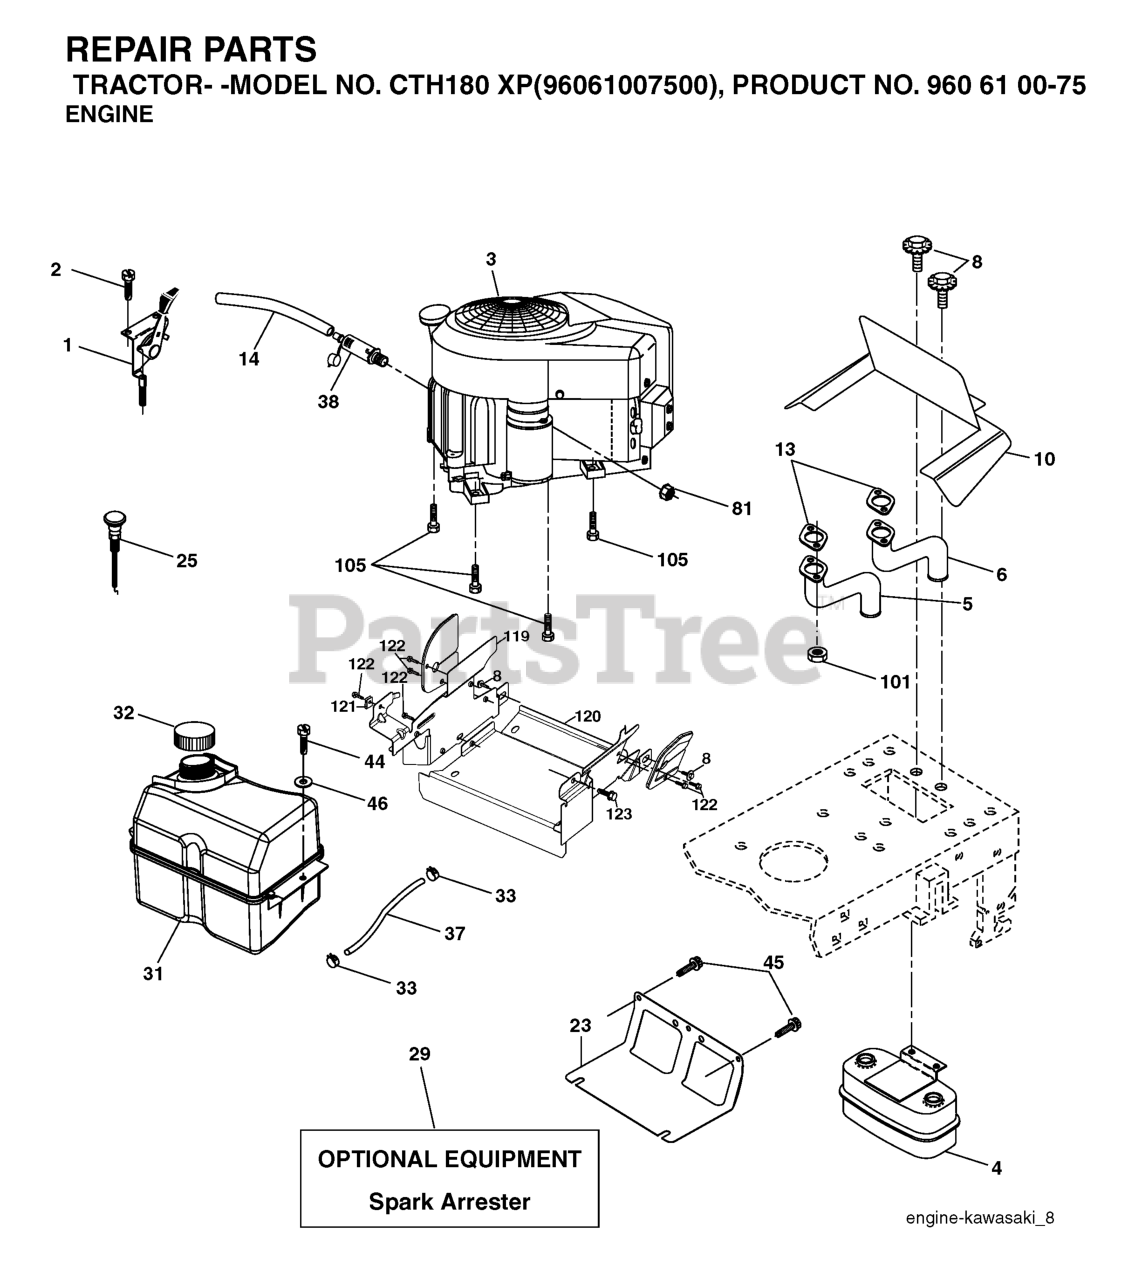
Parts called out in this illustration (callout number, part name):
1	CONTROL, THROTTLE
2	SCREW
4	MUFFLER.TWIN.CYL.LOW.TONE
5	EXHAUST.TUBE.LH.KAWASAKI.
6	EXHAUST.TUBE.RH.KAWASAKI.
8	BOLT.5/16-18UNCX3/4 W/SEMS.BLK
10	RP SHIELD HEAT MUFFLER
14	TUBE, DRAIN OIL ASM.
23	SHIELD.BROWNING.DBR.GUARD
29	KIT.SPARK ARRESTOR 794945 B&S
31	TANK FUEL
32	FUEL CAP
33	HOSE CLAMP
37	LINE.FUEL.20
44	SCREW HEXWSHR 1/4-20X3/4
45	SCREW, 3/8-16X3/4
81	NUT
101	NUT.HEX.FLANGE.TOPLOCK
105	SCREW 3/8-16X1
122	SCREW.1/4-20X5/8
123	SCREW, 5/16-18 X 1/2
